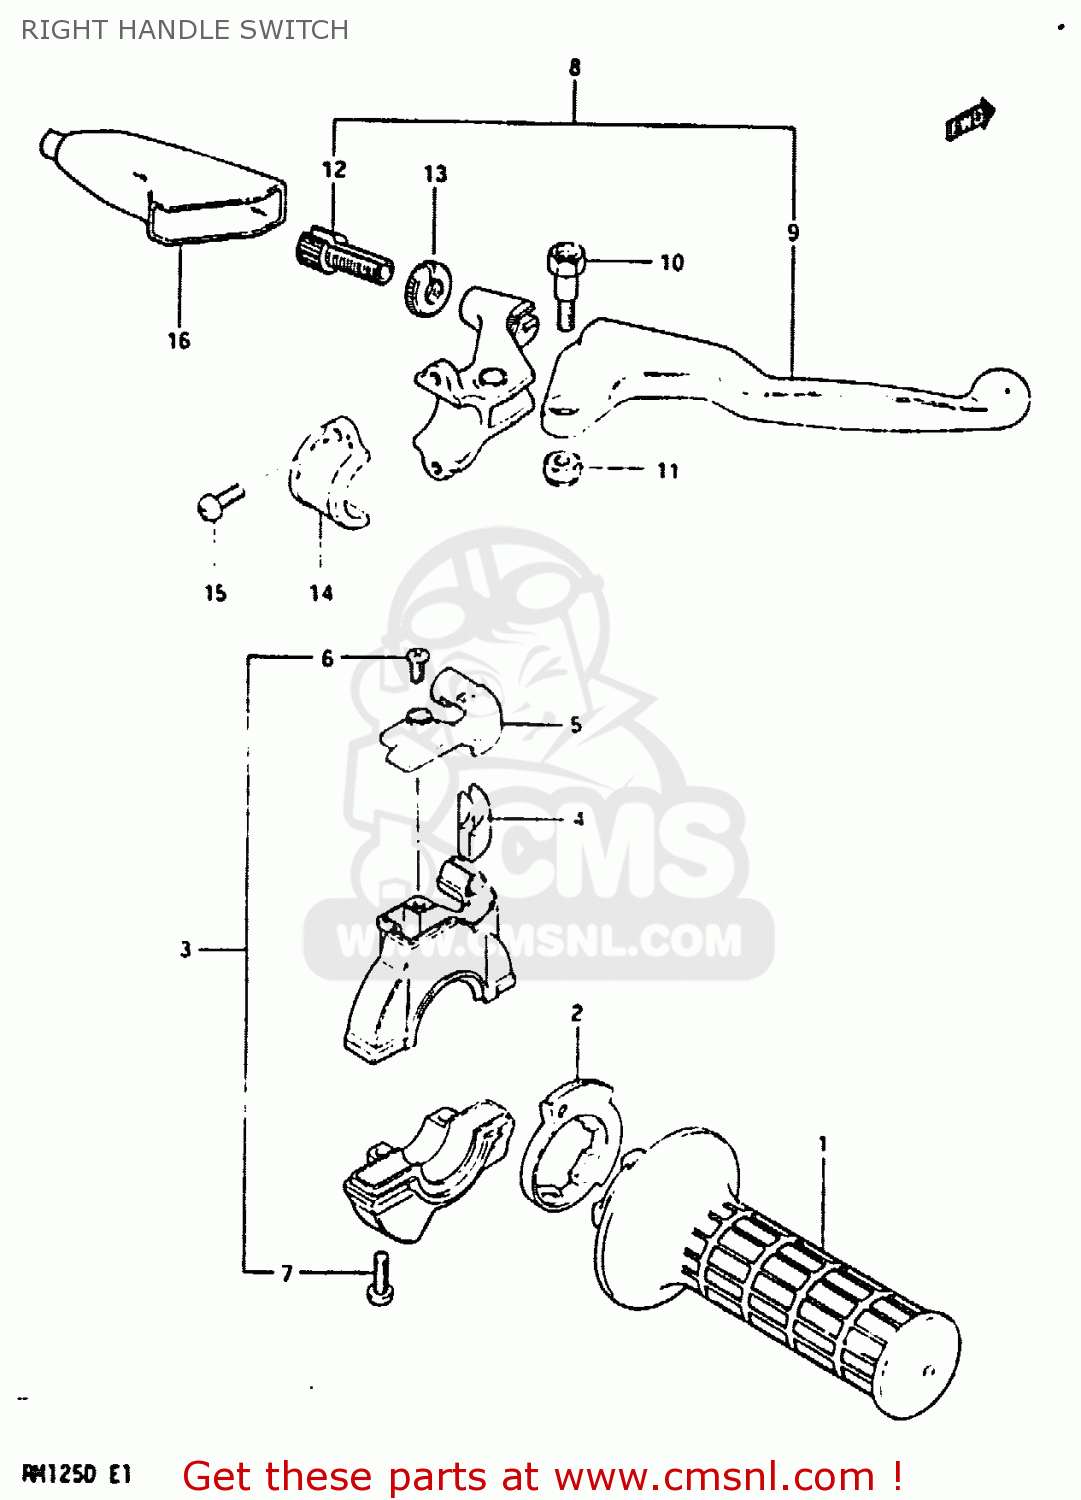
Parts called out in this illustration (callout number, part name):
1	GRIP,THROTTLE
2	ROTOR,THROTTLE GRIP
3	CASE ASSEMBLY,THROTTLE
4	GUIDE PIECE,THROTTLE
5	COVER,THROTTLE CASE
6	SCREW
7	SCREW
8	LEVER ASSEMBLY,BRAKE
9	LEVER,BRAKE
10	BOLT,LEVER
11	NUT 6MM
12	ADJUSTER,CABLE
13	NUT,CABLE ADJUSTER
14	BRACKET,CLUTCH LEVER HOLDER
15	SCREW
16	COVER,CLUTCH LEVER
